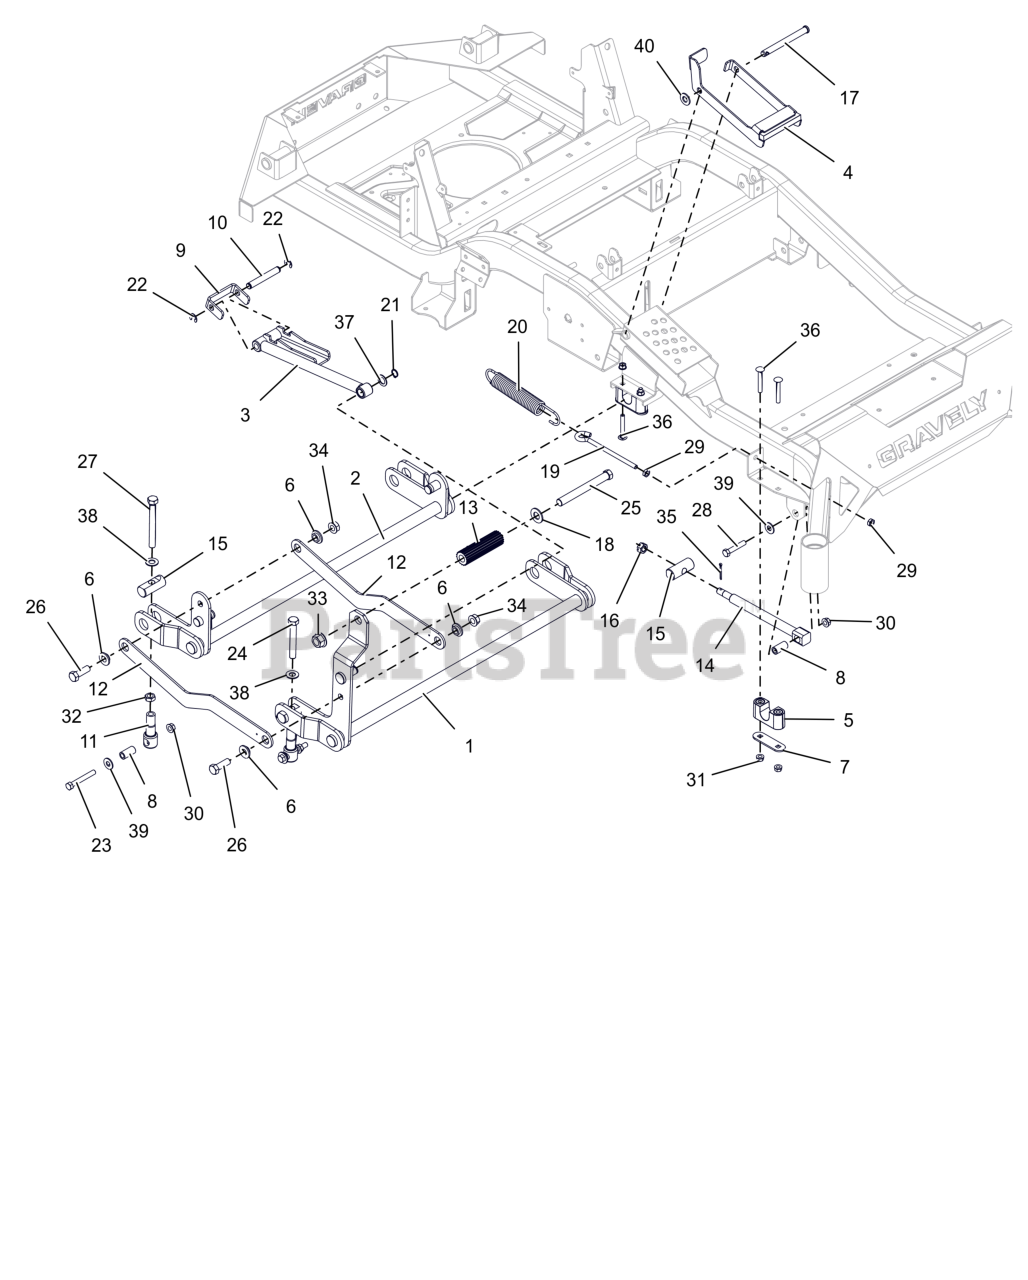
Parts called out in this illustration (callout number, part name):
1	WLDMT, FRONT DECK LIFT PIVOT
2	WLDMT, REAR DECK LIFT PIVOT
3	WLDMT, HOC ARM
4	BRKT, HOC TRANSFER LOCK
5	ASM-BUSHING, DECK LIFT
6	BSHG-FLG .515X.750X.310X1.120
7	PLATE, BEARING SUPPORT
8	SPACER, DECK LEVELING
9	BRKT, HOC LINE
10	ROD, HOC PIVOT
11	LINK, DECK LIFT FORMED
12	LINK, DECK LIFT
13	ROD, FOOT PEDAL (BLACK)
14	DRAG,LINK-HD
15	PIN, DECK LIFT
16	NUT-SL .50-13
17	PIN, SLIC-.500X4.97X4.55 -ZC
18	WSHRFLT 5/8SAE CARBHARD FBP
19	BOLT,.38-16 X 5.25-.62 DIA EYE
20	SG-TENS .162X1.25X8.25 WLD 25
21	RG-RTNG-EXT .625X.050
22	RG-RTNG-EXT .500X.042 (E)
23	BLT, HEX .38-16X2.75 G8 ZCC
24	BLT, HEX 0.5-13X3.5F GR5 ZCC
25	BLT, HEX .62-11X5.50 G5 FBP
26	BLT,HEX .50-13X1.50 G5 ZCC
27	BLT, HEX .50-13X4.50F G8 ZCC
28	BLT,HEX .38-16X2.00 G5 ZCC
29	NUT-JAM .375-16 G2 ZCC
30	NUT-LK-TOP-FLG .38-16 ZC120
31	NUT,LK-CTR-FLG .31-18 GF ZCC
32	NUT-JAM .500-13 G2 ZCC
33	NUT,FLG-TOP LK .625-11 FBP
34	NUT-LK-TOP-FLG .500-13 GF ZCC
35	PIN,CTR.12X1.25EXTPRSQCT ZC120
36	BLT, RHSSN.31-18X2.25 G5 ZCC
37	WSHR, FLT .630X1.005X.062 ZCC
38	WSHR, FLT .557X1.040X.102 ZCC
39	WSHR,FLT .438X1.00X.083 ZCC
40	WSHR,FLT .531X1.062X.095 ZCC
